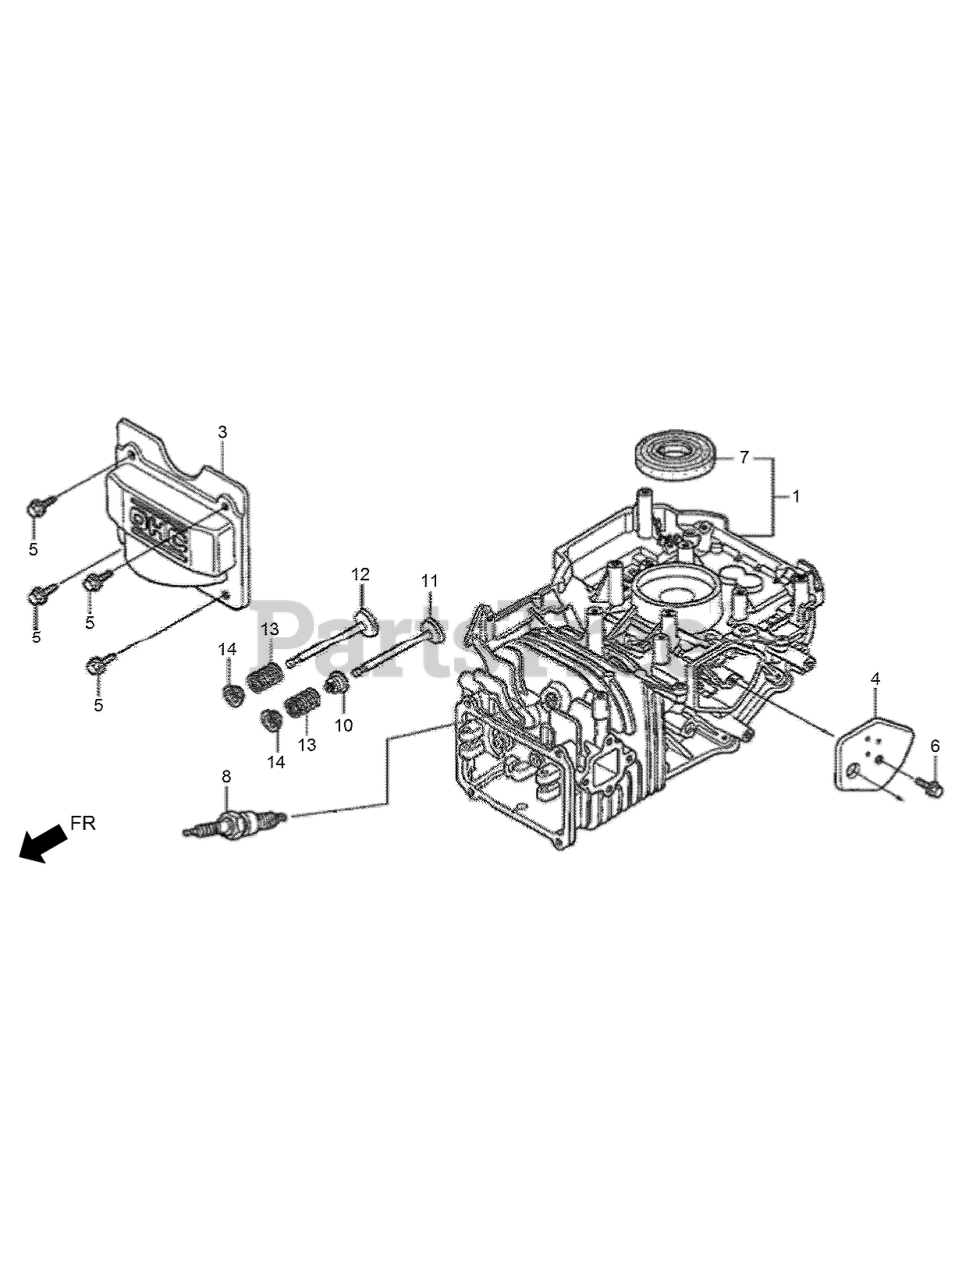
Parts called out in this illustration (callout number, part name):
1	BARREL ASM-CYLINDER (to S/N 3360946)
1	BARREL ASM-CYLINDER (from S/N 3360947)
3	COVER-HEAD
4	BREATHER COVER ASM
5	BOLT-FLANGE-6X12
6	BOLT-FLANGE-6X14
7	OIL SEAL-25.4X62X6
8	SPARKPLUG
10	SEAL-VALVE STEM
11	VALVE-INTAKE
12	VALVE-EXHAUST
13	SPRING-VALVE
14	RETAINER-INTAKE VALVE SPRING
